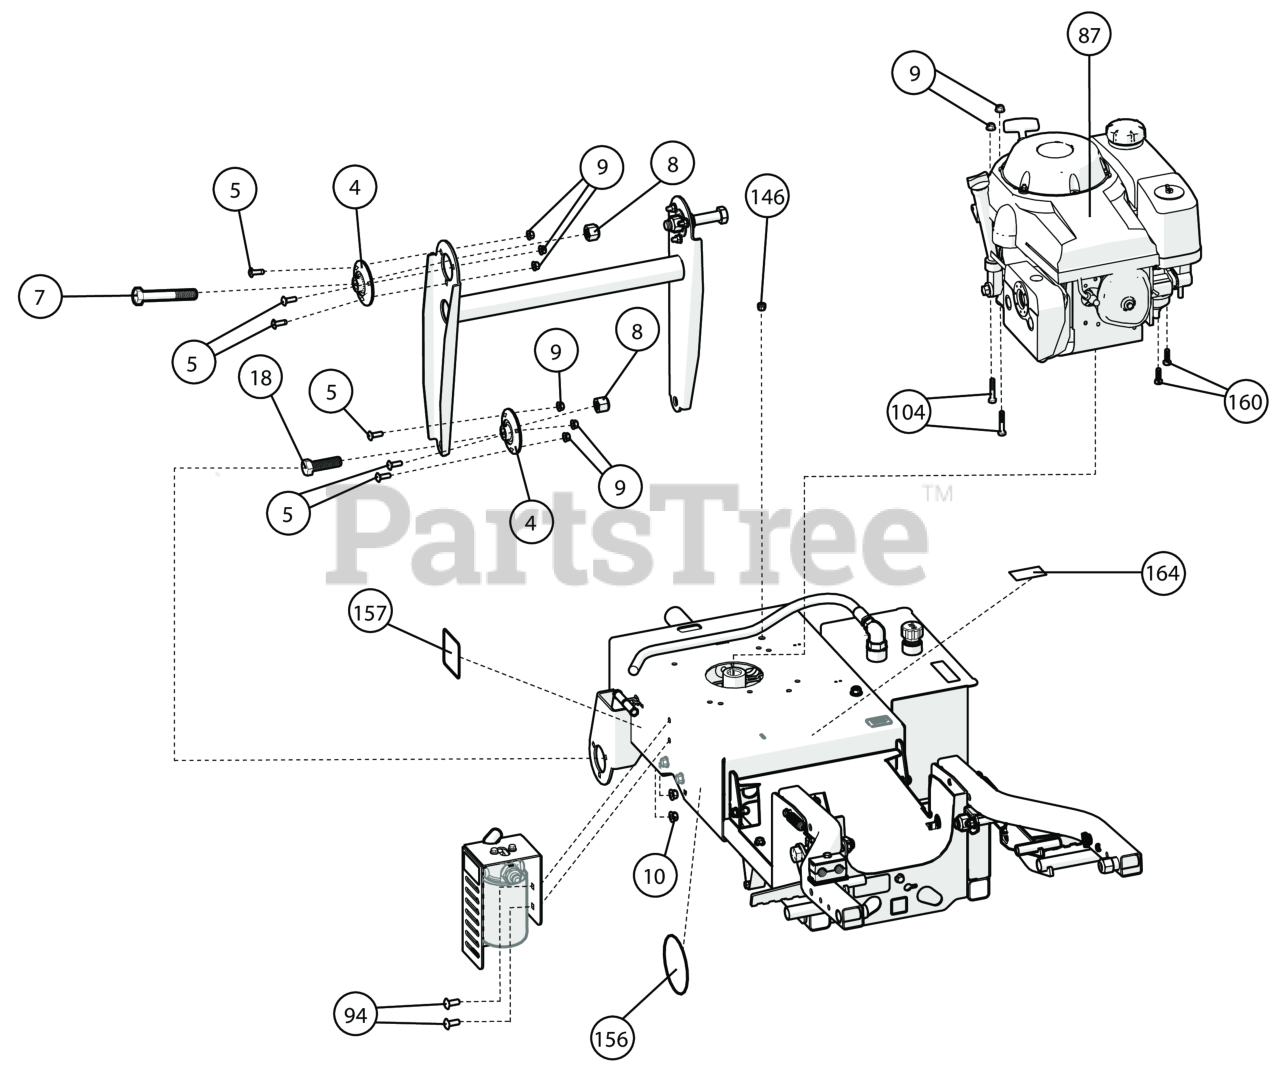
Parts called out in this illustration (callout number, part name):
4	BEARING AND FLANGETTE ASSY .75"
5	BOLT CARRIAGE 5/16"-18 X 1" ZP
7	SCR-CAP, HEX, 3/4-10 X 4.500" ZP
8	NUT LOCK 3/4" - 10 ZP
9	NUT-HEX-NYLK, FLG .3125-18 ZP
10	NUT-HEX-NYLK, FLG .375"-16 ZP
18	SCREWCAP 3/4-10 X 2 1/2" LG Z/P GR 5
87	ENGINE 13HP HONDA GX390UTQA2
94	BOLT CARRAIGE 3/8-16 X 1" ZP
104	SCREWCAP 5/16"-18X1 3/4" HCS ZP
146	BUSHING, SPLIT 0.350" NYLON BLACK
156	LABEL DECAL SM CIRCLE
157	DECAL, DRIVE DISENGAGE
160	SCREWCAP 5/16"-24 X 1" GR.8 ZP W/PATCH
164	DECAL, WARNING, HAND IN BELT, ENG. ONLY
